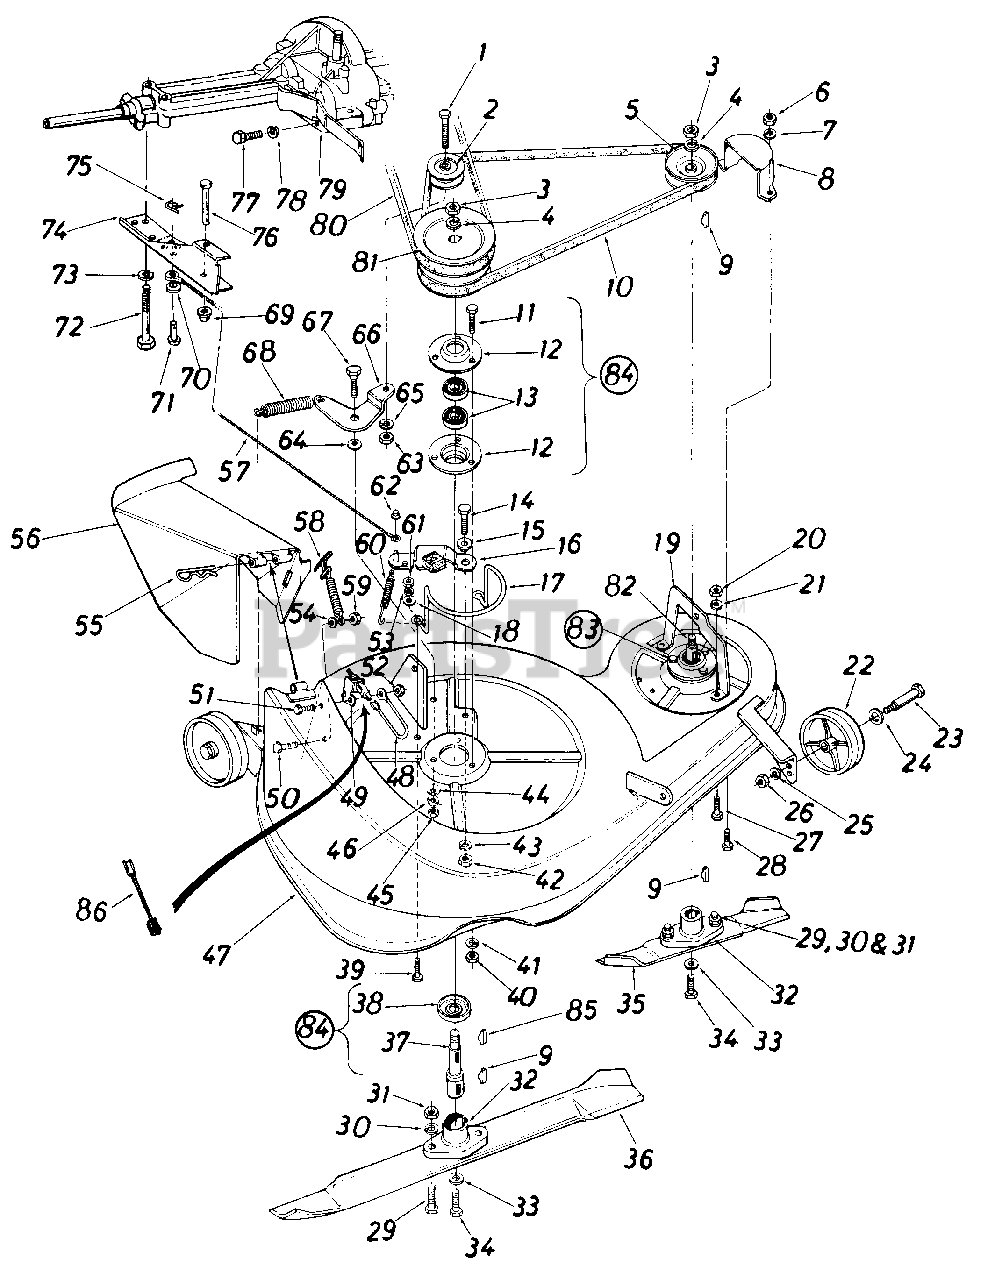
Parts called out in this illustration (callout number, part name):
1	Hex Bolt 3/8-24 x 1.50" Lg.
2	"V"-ldler Pulley 3.06" O.D.
3	Hex Jam Nut 5/8-18 Thd.
4	Bell-Wash. .630" I.D. x 1.25 x .090
5	Pulley 3.56" O.D. x 5/8
6	Hex Nut 1/4-20 Thd.
7	L-Wash. 1/4" I.D.
8	Belt Guard Cover
9	#6 Hi-Pro Key 5/32 x 5/8" Dia.
10	1 V-Belt 1/2 x 53" Lg. (4L)
11	Hex Bolt 5/16-18 x .75" Lg.
12	Brg. Housing 1.85" I.D.
13	Ball Bearing .787" I.D. x 1.85" O.D.
14	Hex Bolt 5/16-18 x 1.0" Lg. Grade 5
15	Shld. Spacer.500" Dia. x .27" Lg.
16	Blade Brake Brk't. Ass'y.
17	Belt Guard
18	Fl-Wash. .344" I.D. x .875" O.D.
19	Deck Bracket
20	Hex Nut 5/16-18 Thd.*
21	L-Wash. 5/16 I.D.
22	Deck Wheel 5.0" x 1.38"
23	Shoulder Bolt .498" Dia. x 1 .635
24	Belleville .400" I.D. x .88" O.D.
25	L-Wash. 3/8 I.D.
26	Hex Nut 3/8-16 Thd.
27	Hex Bolt 5/16-18 x .75" Lg.
28	Hex Bolt 1/4-20 x .62" Lg.
29	Hex Bolt 5/16-24 x 1.00" Lg. Grade 5
30	L-Wash. 5/16" I.D.
31	Hex Nut 5/16-24 Thd.
32	Blade Adapter
33	L-Wash. 3/8 I.D. H.D.
34	Hex Bolt 3/8-24 x 1.50" Lg. Grade 5
35	13" Blade
36	24" Blade
37	Blade Spindle
38	Bearing Shield
39	Hex Bolt 5/16-18 x .75" Lg.
40	Hex Nut 5/16-18 Thd.
41	L-Wash. 5/16n l.D.
42	Hex Nut 5/16-18 Thd.
43	L-Wash. 5/16" I.D.
44	Hex Nut 5/16-18 Thd.
45	Hex Nut 5/16-18 Thd.
46	L-Wash. 5/16" I.D.
47	36" Deck Ass'y.
48	Ground Wire
49	Safety Switch
50	Truss Mach. Scr. 1/4-20 x .50" Lg.
51	Hex Bolt 1/4-20 x .62" Lg.
52	Hex Nut 1/4-20 Thd.
53	L-Wash. 5/16" I.D.
54	Fl-Wash. .281" I.D. x .50" O.D.
55	Internal Cotter Pin
56	Chute Deflector
57	Brake Cable Ass'y. (13.75" Lg.)
58	Spring Latch Ass'y.
59	Hex Nut 1/4-20 Thd.
60	Extension Spring .38" O.D. x 3.25" Lg.
61	Hex Nut 5/16-18 Thd.
62	Cap Speed Nut 1/4" Rod
63	Hex Nut 3/8-16 Thd.
64	Fl-Wash. .344" I.D. x .875" O.D.
65	L-Wash. 3/8" I.D.
66	Deck Idler Brk't. Ass'y.
67	Shoulder Bolt .498" Dia. x .71 0
68	Extension Spring
69	Cap Speed Nut 1/4" Rod
70	Fl-Wash. .281" I.D. x .50" O.D.
71	Clevis Pin 1/4" Dia. x .53" Lg.
72	Hex Bolt 5/16-18 x 2.75" Lg.*
73	L-Wash. 5/16" I.D.
74	Lower Outside Belt Guard
75	Intern. Cot-Pin 5/16" Dia.
76	Weld Pin .25" Dia. x 2.5" Lg.
77	Hex Bolt 1/4-20 x .62" Lg.
78	L-Wash. 1/4" I.D.
79	Lower Inside Belt Guard
80	V-Belt 1/2 x 50" Lg.
81	Pulley 5.81" O.D. x 5/8
82	Blade Spindle (3.70" Lg.)
83	Spindle Ass'y.
84	Spindle Ass'y.
85	#61 Hi-Pro Key 3/16" x 5/8" Dia.
86	Wire Lead
